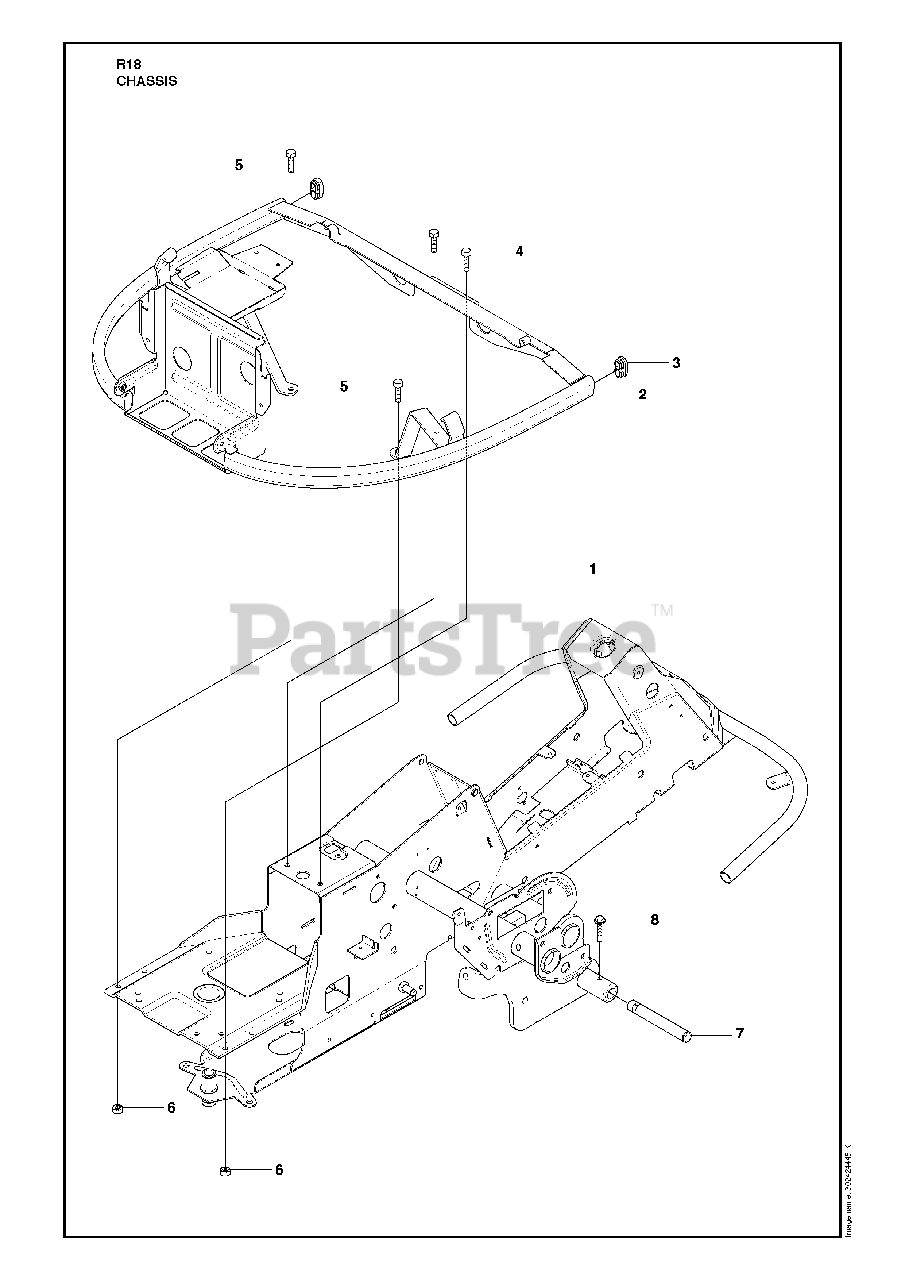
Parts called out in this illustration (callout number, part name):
2	ENGINE FRAME
6	LOCKNUT M8
8	BOLT FLANGE - M8X40\
